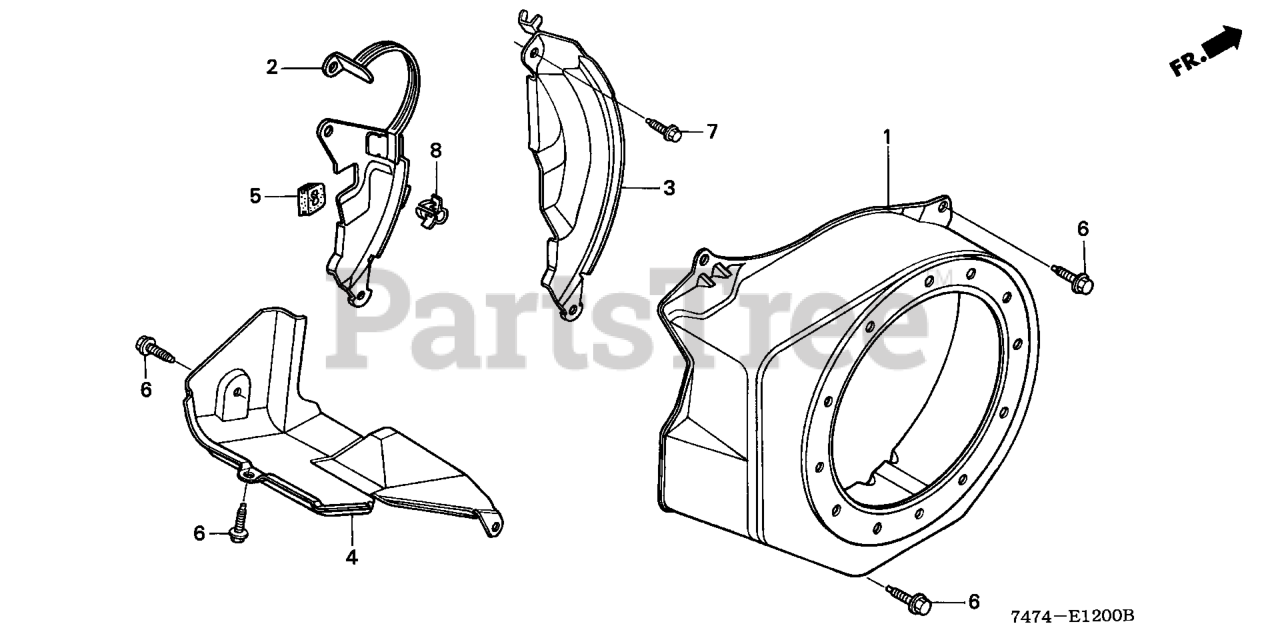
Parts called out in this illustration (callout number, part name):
1	COVER, FAN *R280* (POWER RED)
2	PLATE, SIDE (A.C. SEL)
4	SHROUD
5	GROMMET, WIRE
6	BOLT, FLANGE (6X12) (CT200)
